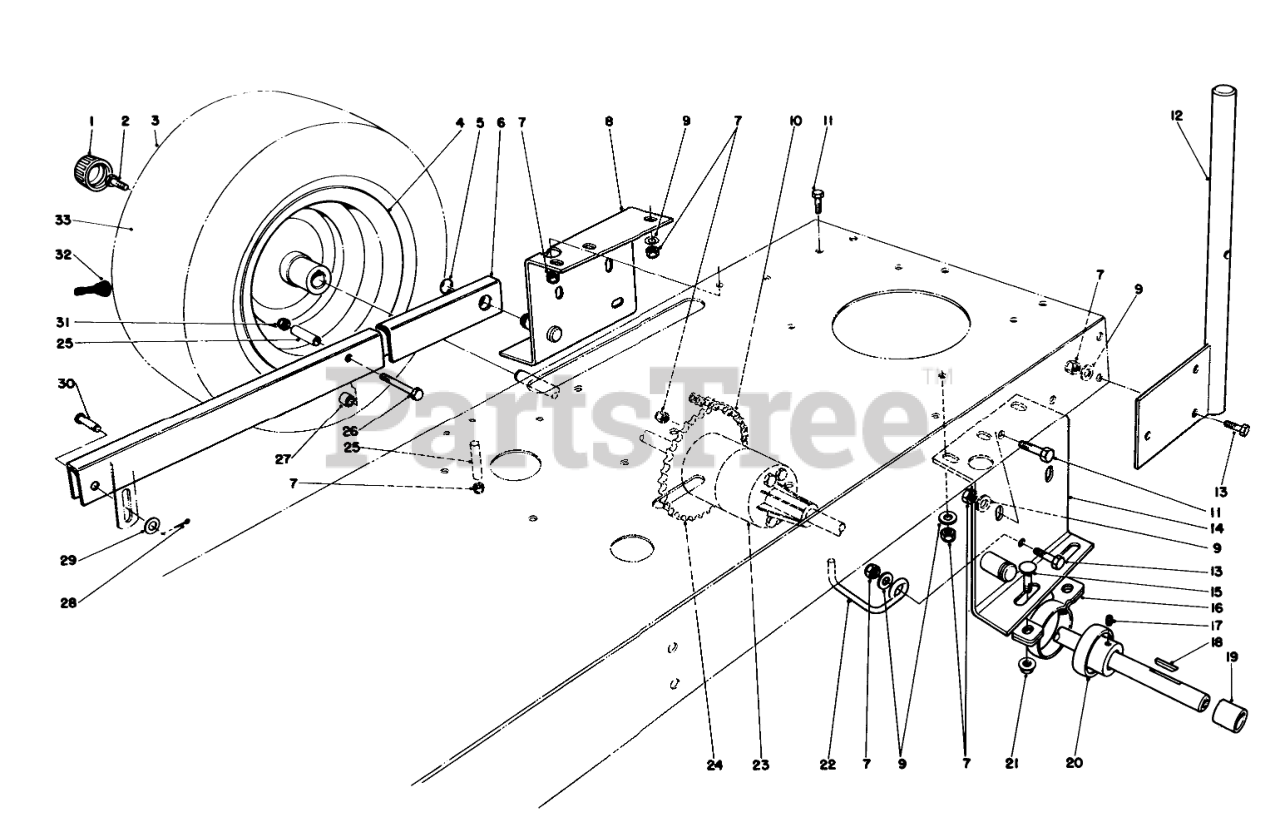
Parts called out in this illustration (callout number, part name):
1	Cap-Hub
2	CAPSCREW 3/8 16 3/4
3	Tire
4	REAR RIM
5	E-RING
6	REAR SUSP ARMR
7	NUT-LOCK, NI
8	Support-Rear Axle R.H.
9	WASHER-PLAIN
10	Chain
11	SCREW-HH
12	Stand Bar
13	SCREW-HH
14	Support-Rear Axle L.H.
15	SCREW-CARR
16	RTNR-PILLOW BLK
17	SCREW-SET, HSH
17	SCREW-SET
19	REAR AXLE SPACER
20	Bearing-Self Aligning (Incl. Ref. #17)
21	NUT-HF
22	BELT GUIDE
23	Differential
24	Sprocket Differential
25	OUTER TUBE SPACER
26	SCREW-HH
27	INNER TUBE SPACER
28	PIN-COTTER
29	WASHER-FLAT
30	PIN-CLEVIS
31	NUT-LOCK, CONE
32	STEM-VALVE
33	TUBE-INNER
